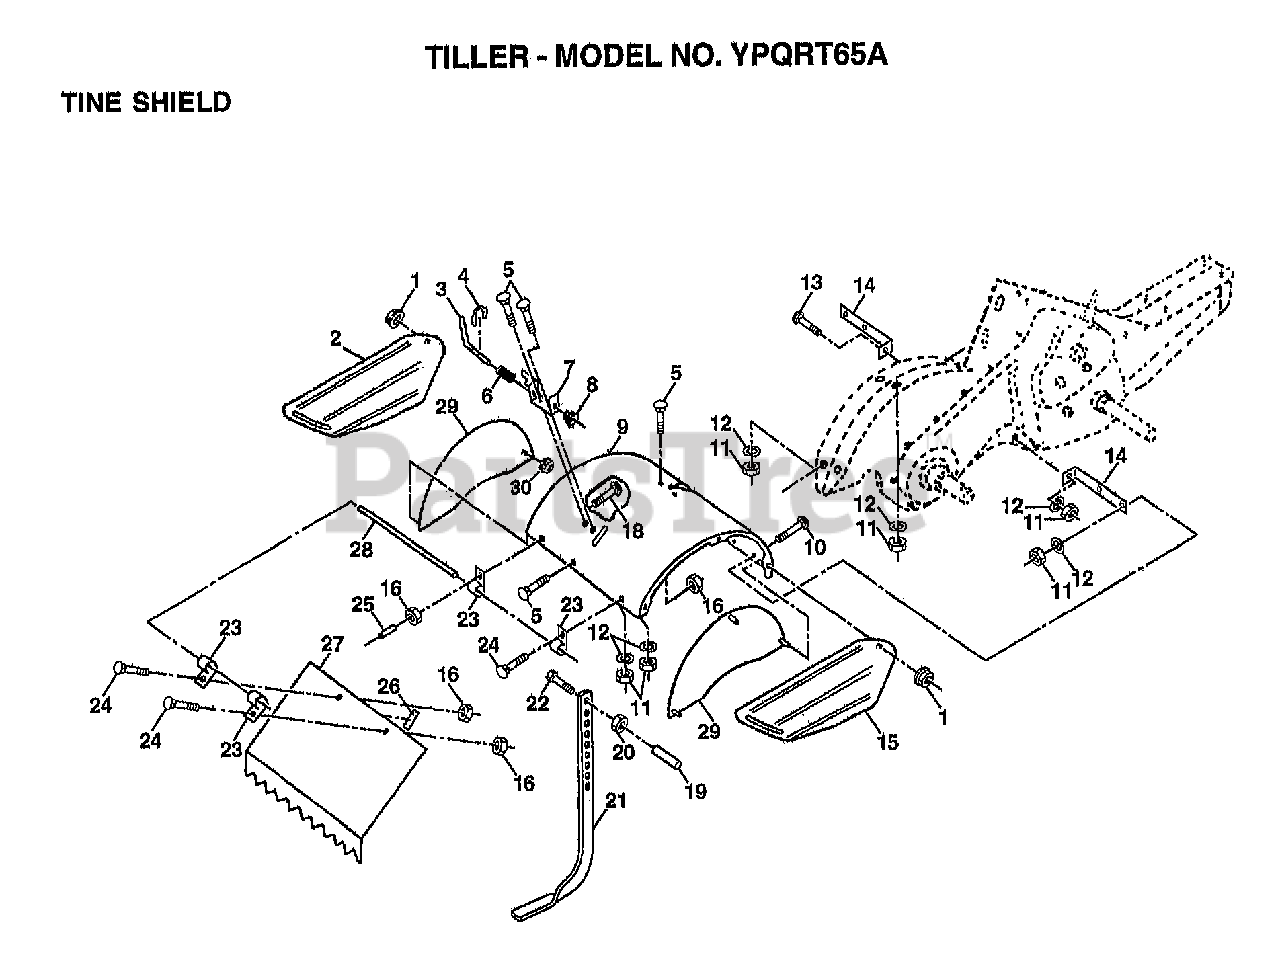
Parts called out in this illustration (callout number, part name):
1	NUT
2	SHLD.SIDE.OUTER.L
3	STAKE PIN TI
4	KLIP RING TI
5	BOLT
6	SPRING TI
7	LATCH BRACKET TI
8	SPRING CRT
9	SHIELD TINE
10	BOLT
11	NUT.HEX.5/16-18
12	LOCKWASHER
13	BOLT
14	"BRACKET,SHIELD"
15	SHLD.SIDE.OUTER.R
16	NUT
18	BOLT
19	GRIP CRT
20	NUT.HEX.3/8-16UNC
22	BOLT
23	HINGE CRT
24	BOLT
25	VINYL CAP TI
26	PAD IDLER TI
27	"SHIELD,LEVEL"
28	PIN HINGE
29	SHIELD TINE
30	LOCKNUT TI
